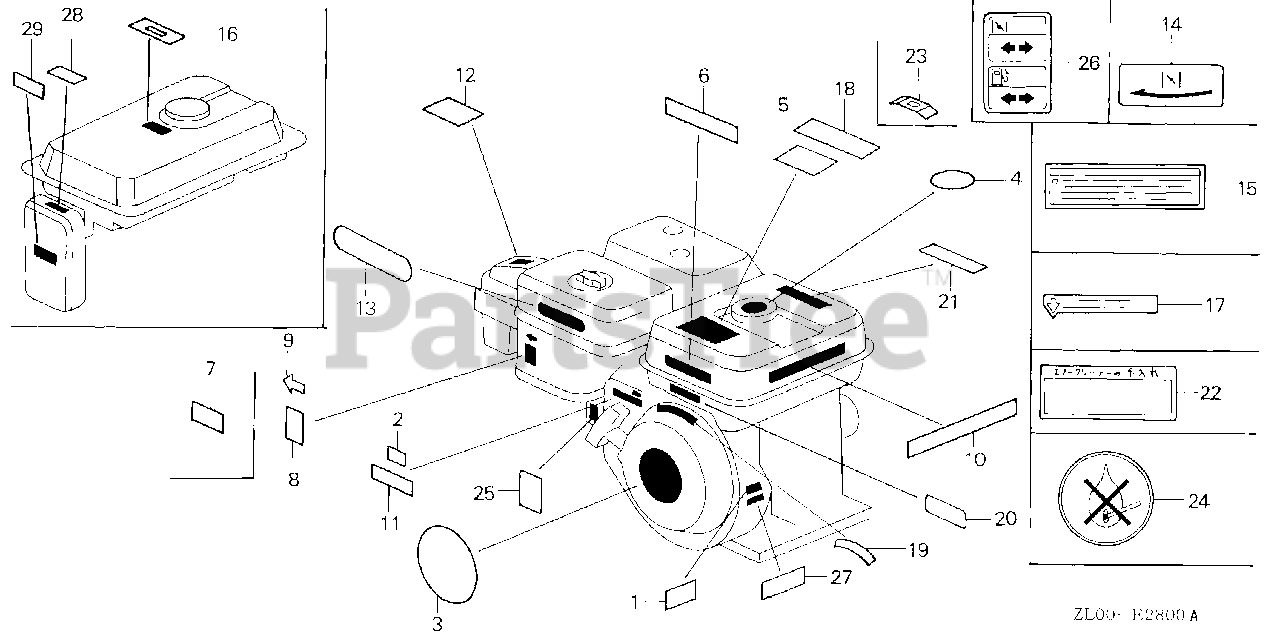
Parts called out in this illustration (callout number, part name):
3	EMBLEM
6	LABEL, CAUTION
10	MARK, OIL ALERT (E)
12	LABEL, AIR CLEANER CAUTION
13	MARK, AIR CLEANER SALES POINT
19	LABEL, CAUTION
23	MARK, FUEL (EXTERNAL)
